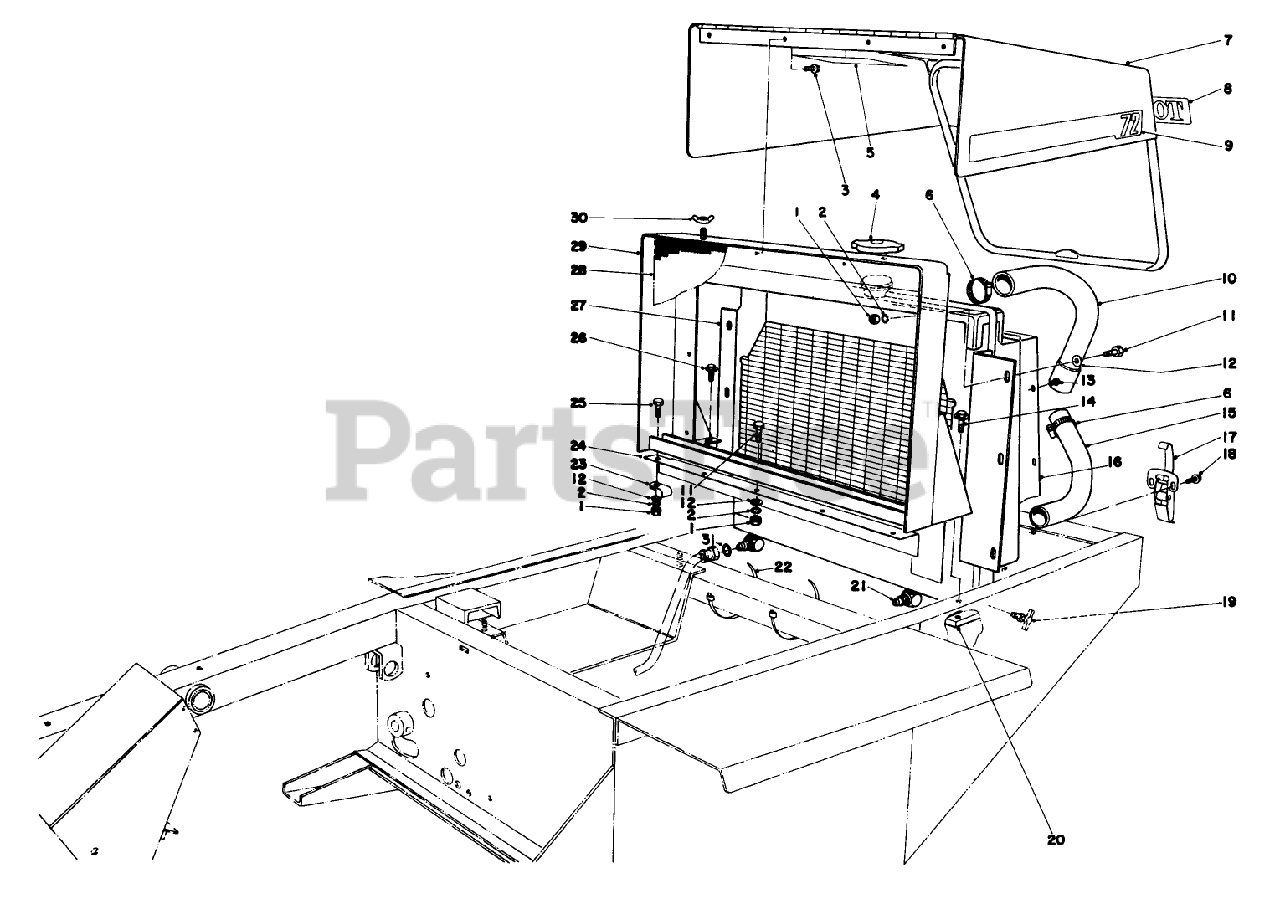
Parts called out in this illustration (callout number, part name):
1	NUT-HEX
2	WASHER-LOCK
3	SCREW-HWH
4	RAD PRESS CAP ASM
5	Decal
6	CLAMP-HOSE
7	Hood
8	Decal
9	DECAL
10	UPPER HOSE
11	SCREW-HH
12	WASHER-PLAIN
13	SCREW-THD FRM,HWH
14	SCREW-HHF
15	LOWER HOSE
16	Radiator Shroud
17	CLAMP-SLOTTED
18	10-24 X 1/2 SEMS SCR
19	DRAINCOCK
20	LH FRAME BAR
21	ELBOW
22	TIE-CABLE
23	CLAMP-R
24	Sealing Plate Grill
25	SCREW-HH
26	SCREW-HWHTF
27	RADIATOR ASM
28	GRILLE WA R
29	Radiator Support
30	NUT-WING
31	WASHER SPECIAL
